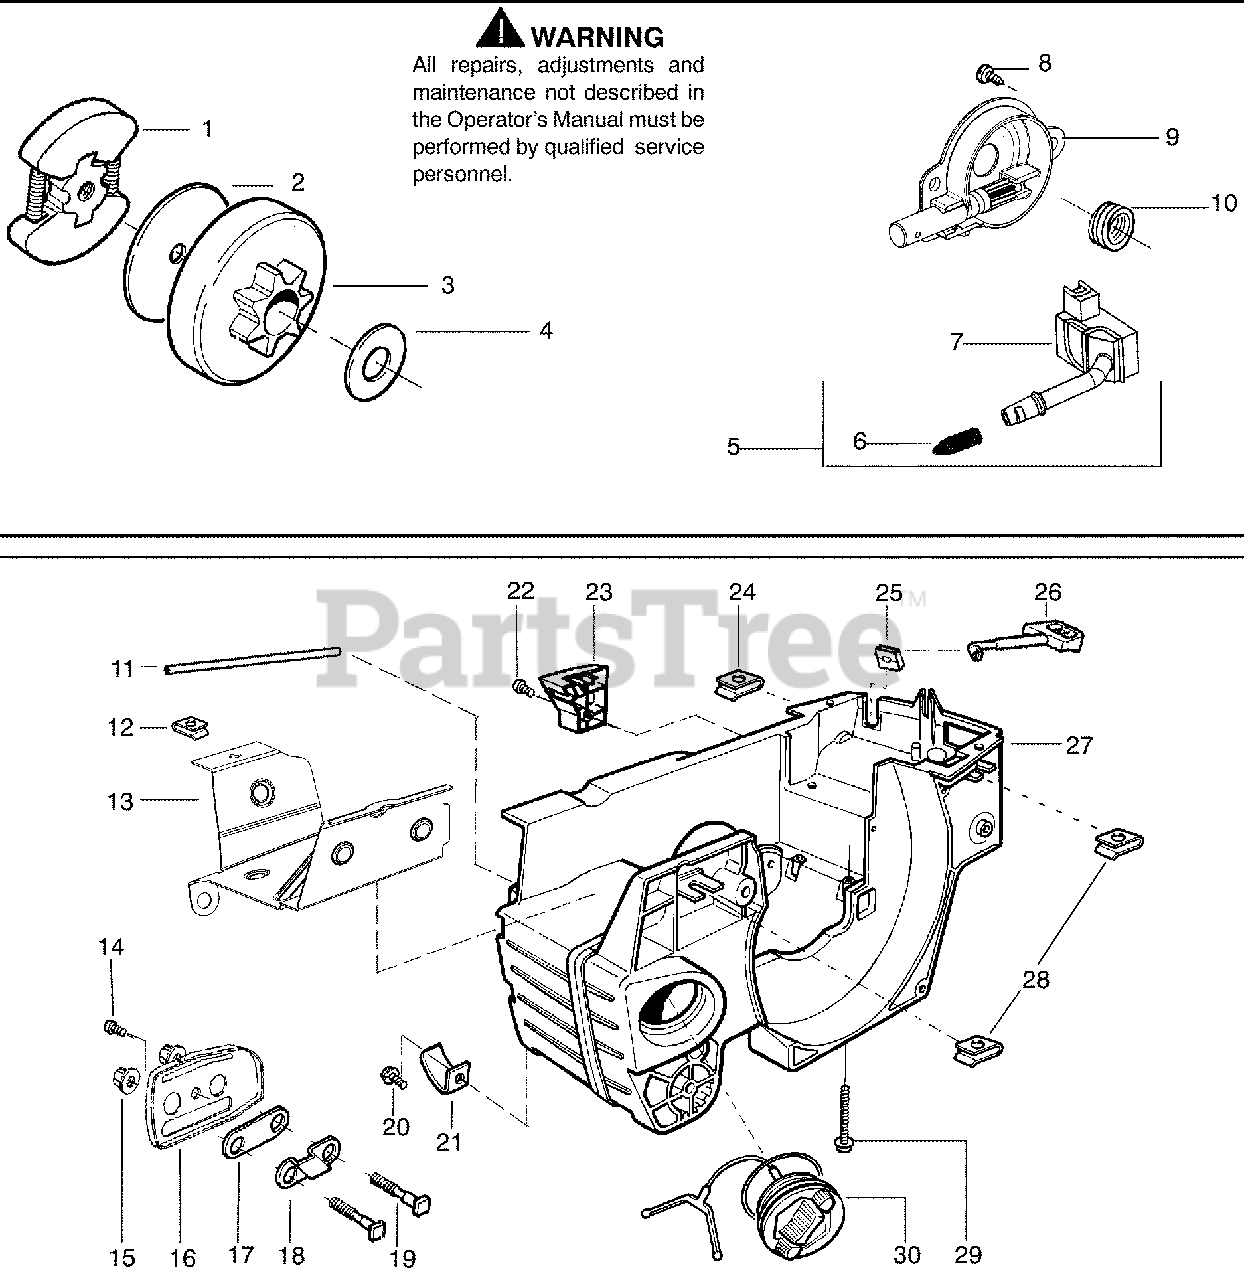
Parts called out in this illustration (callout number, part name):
1	Assy--Clutch
2	Washer--Clutch
3	Assy--Clutch Drum w/Bearing
4	Washer--Thrust
5	Assy--Oil Pick--Up and Screen
6	Filter--Oil
7	Assy--Pickup
9	Assy--Oil Pump
10	Worm Gear--Oil Pump
11	Tube--Oil Vent
12	Clip--Retainer
13	Shield--Heat
14	Screw
16	Plate--Bar
18	Plate--Bar Stud
21	Chain Catcher
24	Nut--Type "U" Speed
26	Lever--Choke
27	Kit -- Chassis Ass’y.
28	Nut--Type "U" Speed
30	Assy.-- Oil Tank Cap
